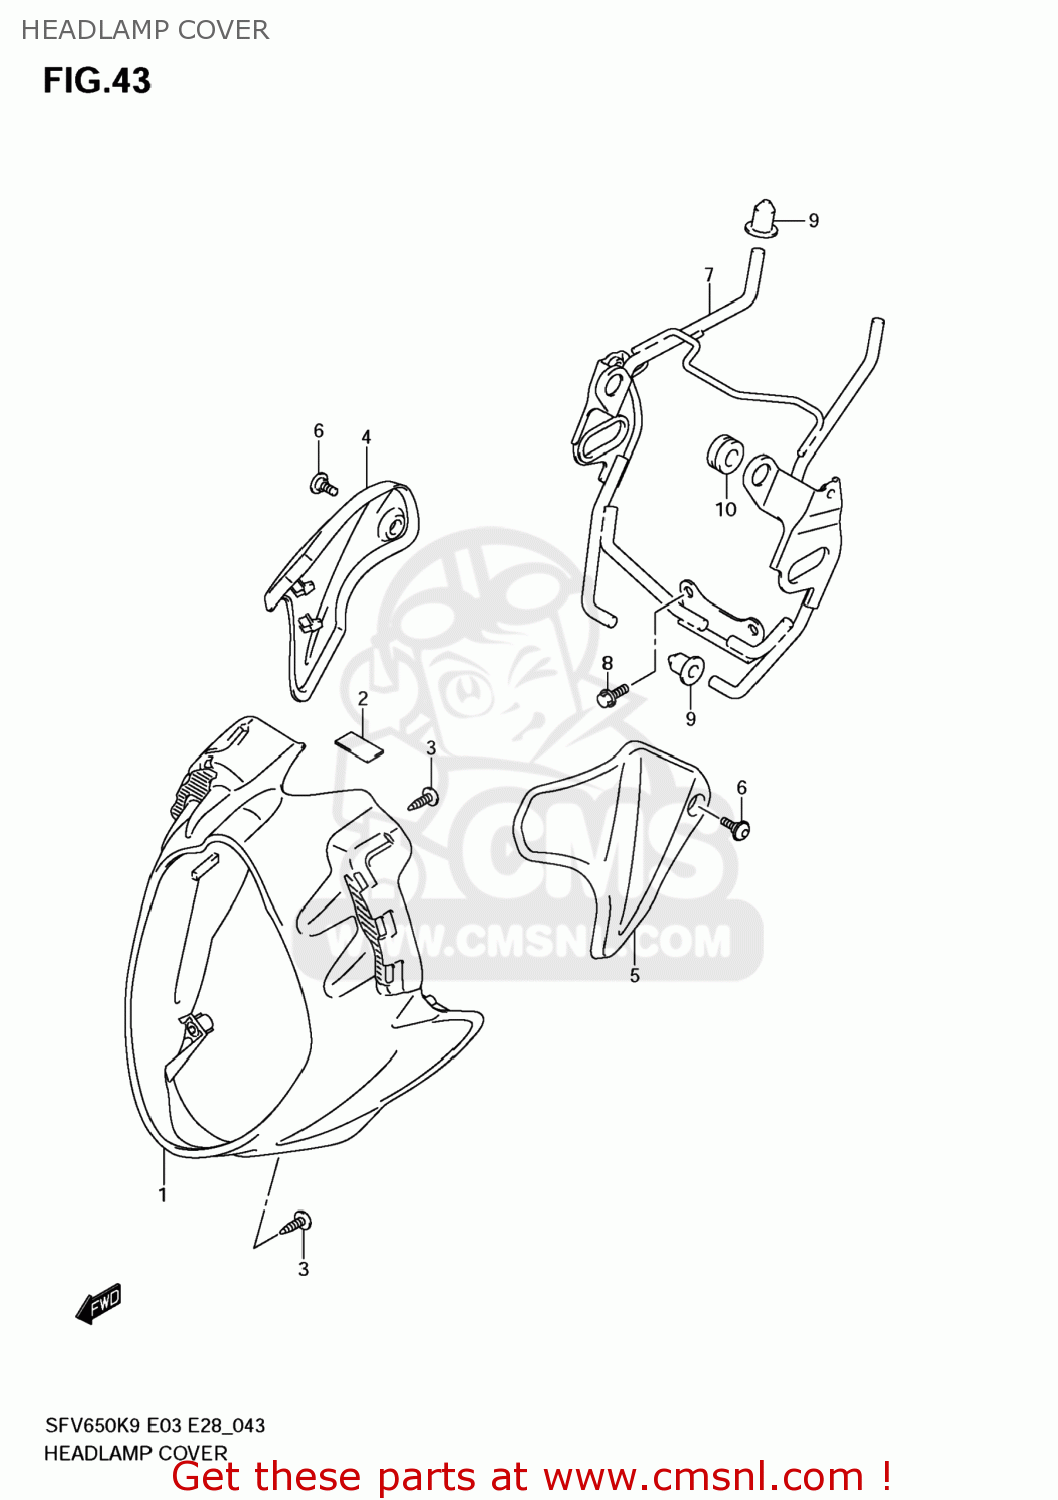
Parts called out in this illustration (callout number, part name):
1	COVER,HEADLAMP
2	CUSHION,FUEL TANK NO.2
3	SCREW
4	COVER,HEADLAMP,R
5	COVER,HEADLAMP,L
6	SCREW(5X13)
7	BRACE,HEADLAMP HOUSING
8	BOLT
9	CUSHION,HEADLAMP HOUSING BRACE
10	CUSHION
